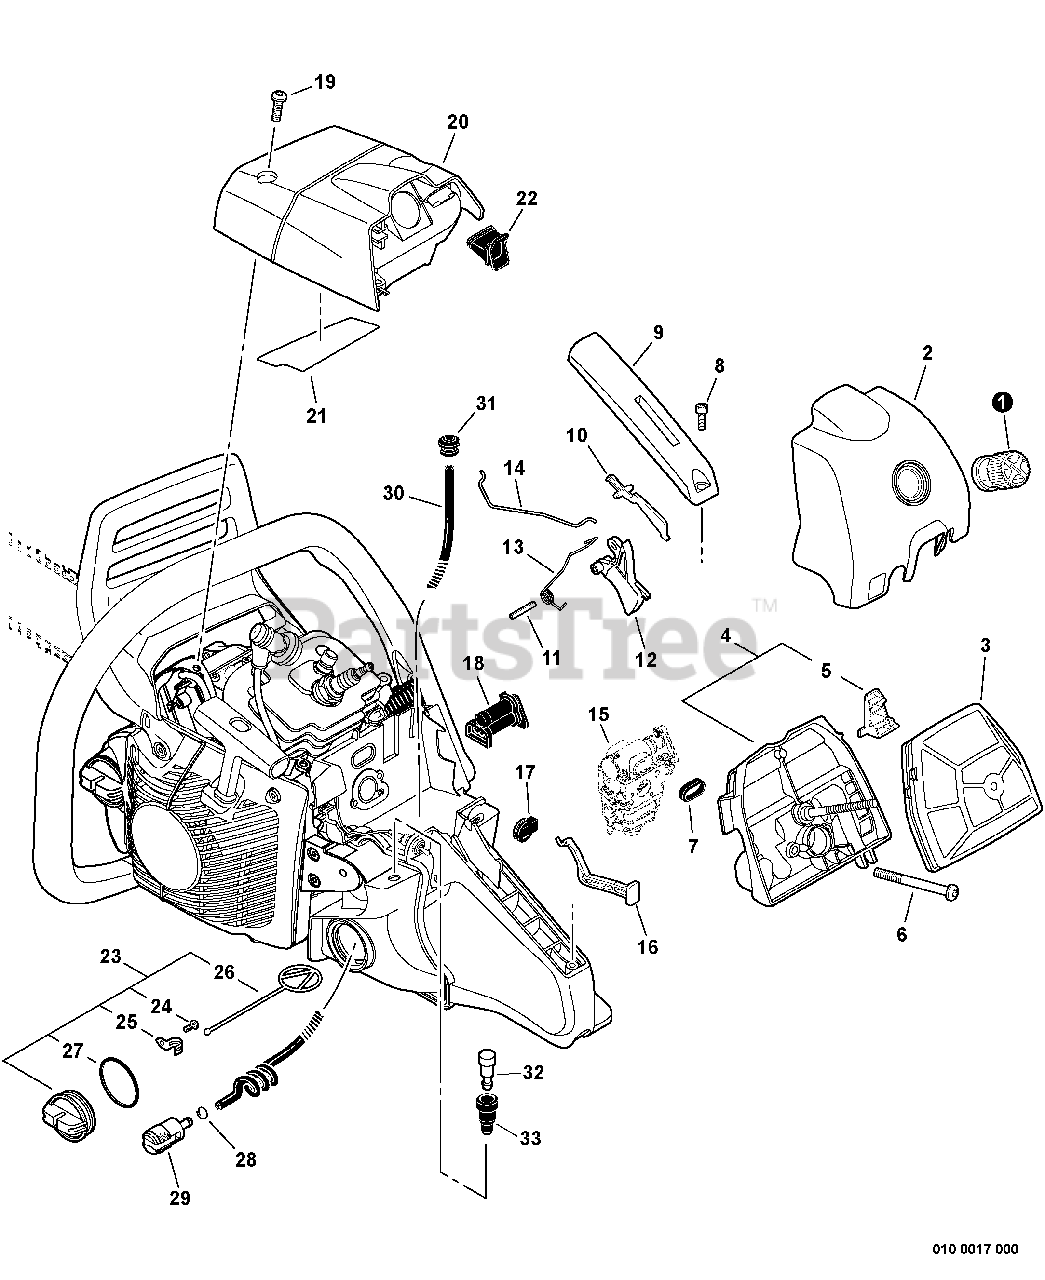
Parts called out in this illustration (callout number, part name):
1	THUMBSCREW
2	COVER, AIR FILTER
3	FILTER, AIR
4	AIR FILTER CASE KIT
5	GUIDE, AIR
6	SCREW - 5X50
7	COVER, DUST
8	SCREW - 4X12
9	COVER, HANDLE
10	LEVER, TRIGGER LOCKOUT
11	PIN - SPRING -- 4X25
12	TRIGGER, THROTTLE
13	SPRING, TRIGGER
14	ROD, THROTTLE
15	CARBURETOR
16	ROD, CHOKE
17	GROMMET
18	GROMMET
19	SCREW - 5X16
20	COVER, ENGINE
21	DEFLECTOR, HEAT
22	DUCT, AIR
23	CAP ASSY
24	SCREW - 3X8
25	RETAINER
26	CONNECTOR, CAP
27	O-RING - 29
28	CLIP - 6
29	FILTER, FUEL
30	PIPE, FUEL - SPIRAL
31	GROMMET
32	VENT, FUEL TANK
33	HOLDER, VENT
